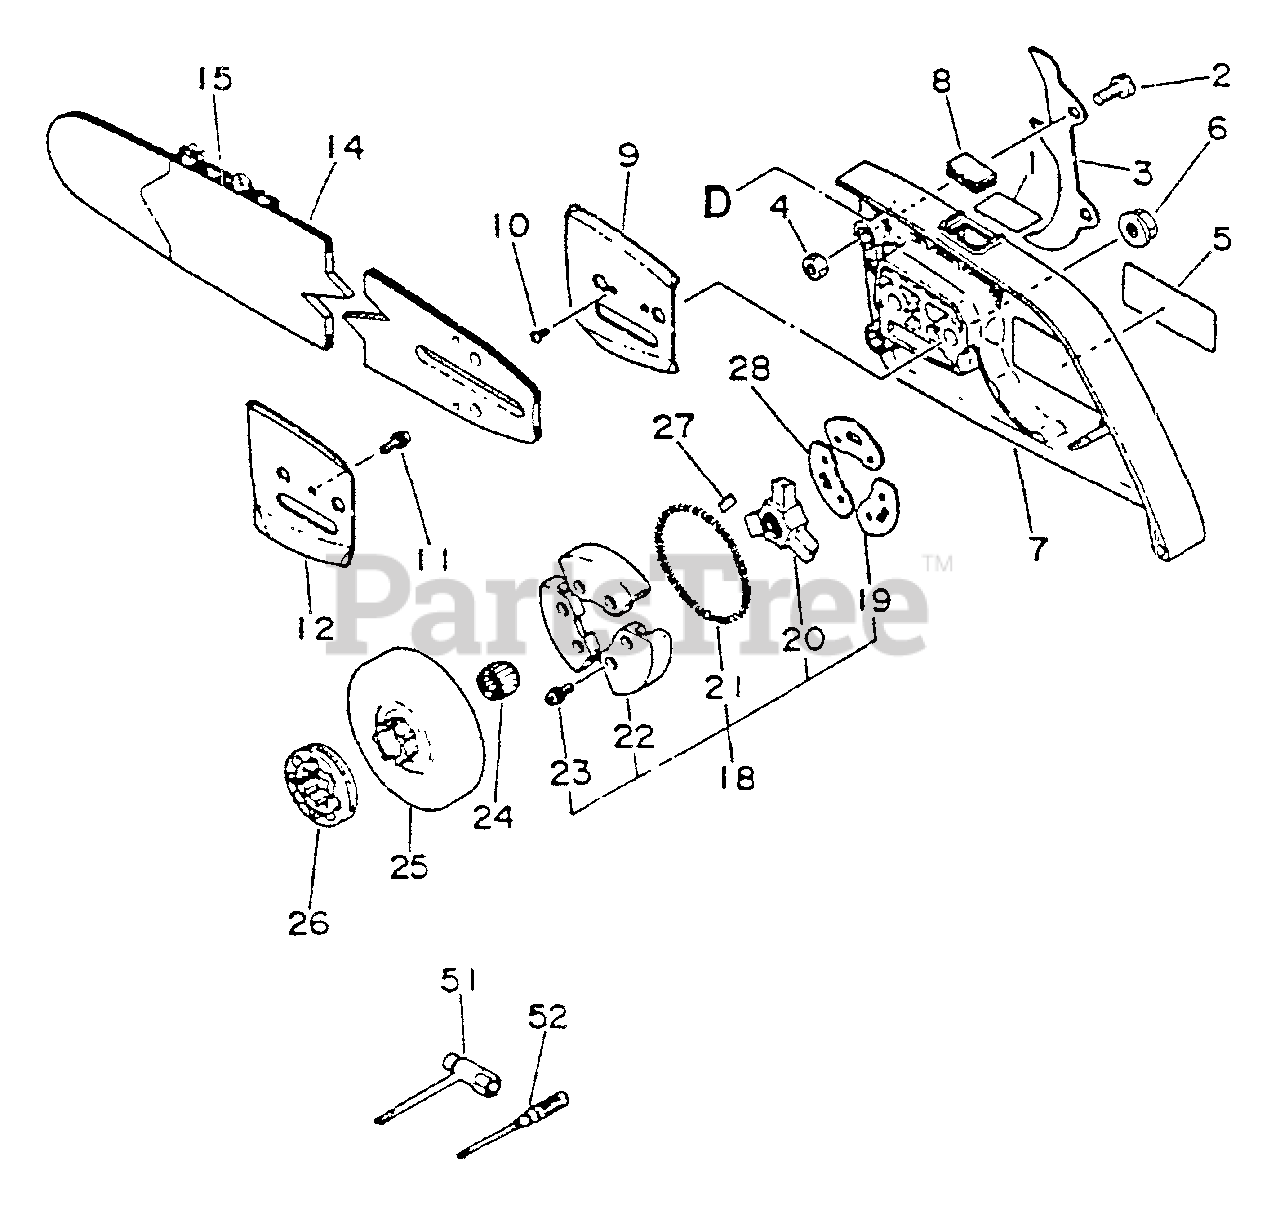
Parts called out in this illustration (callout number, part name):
1	LABEL - CAUTION
4	LOCKNUT - 6
5	LABEL - ECHO
6	NUT - FLANGE
7	GUARD, SPROCKET
9	PLATE, GUIDE - OUTER
10	SCREW - 3X6
11	SCREW - 4X10
12	PLATE, GUIDE - INNER
14	GUIDE BAR
15	CHAIN, SAW
18	CLUTCH ASSY
19	PLATE, CLUTCH
20	HUB, CLUTCH
21	SPRING, CLUTCH
22	CLUTCH SHOE SET
23	SCREW - 4X10
24	BEARING, NEEDLE
25	DRUM, CLUTCH
26	SPROCKET, RIM
27	PLATE, SPRING
28	PLATE, CLUTCH
51	T-WRENCH - 13X19mm
52	SCREWDRIVER
